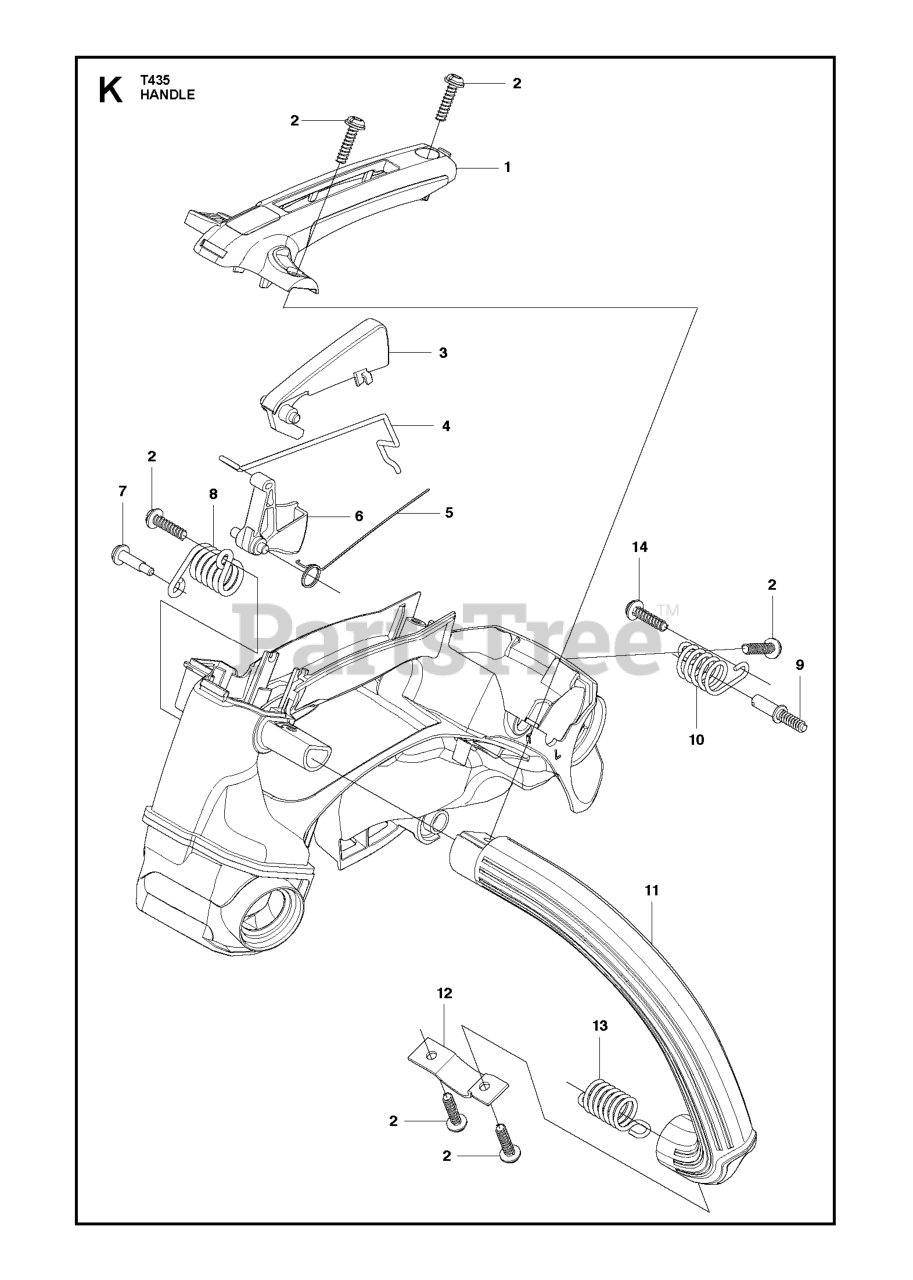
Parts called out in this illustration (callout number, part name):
1	COVER GRIP
5	SPRING
8	SPRING, FRONT
9	%BOLT
10	SPRING, PTO
11	HANDLE (L)
13	DAMPER, MAG
14	SCREW (RPLS 267132210)
